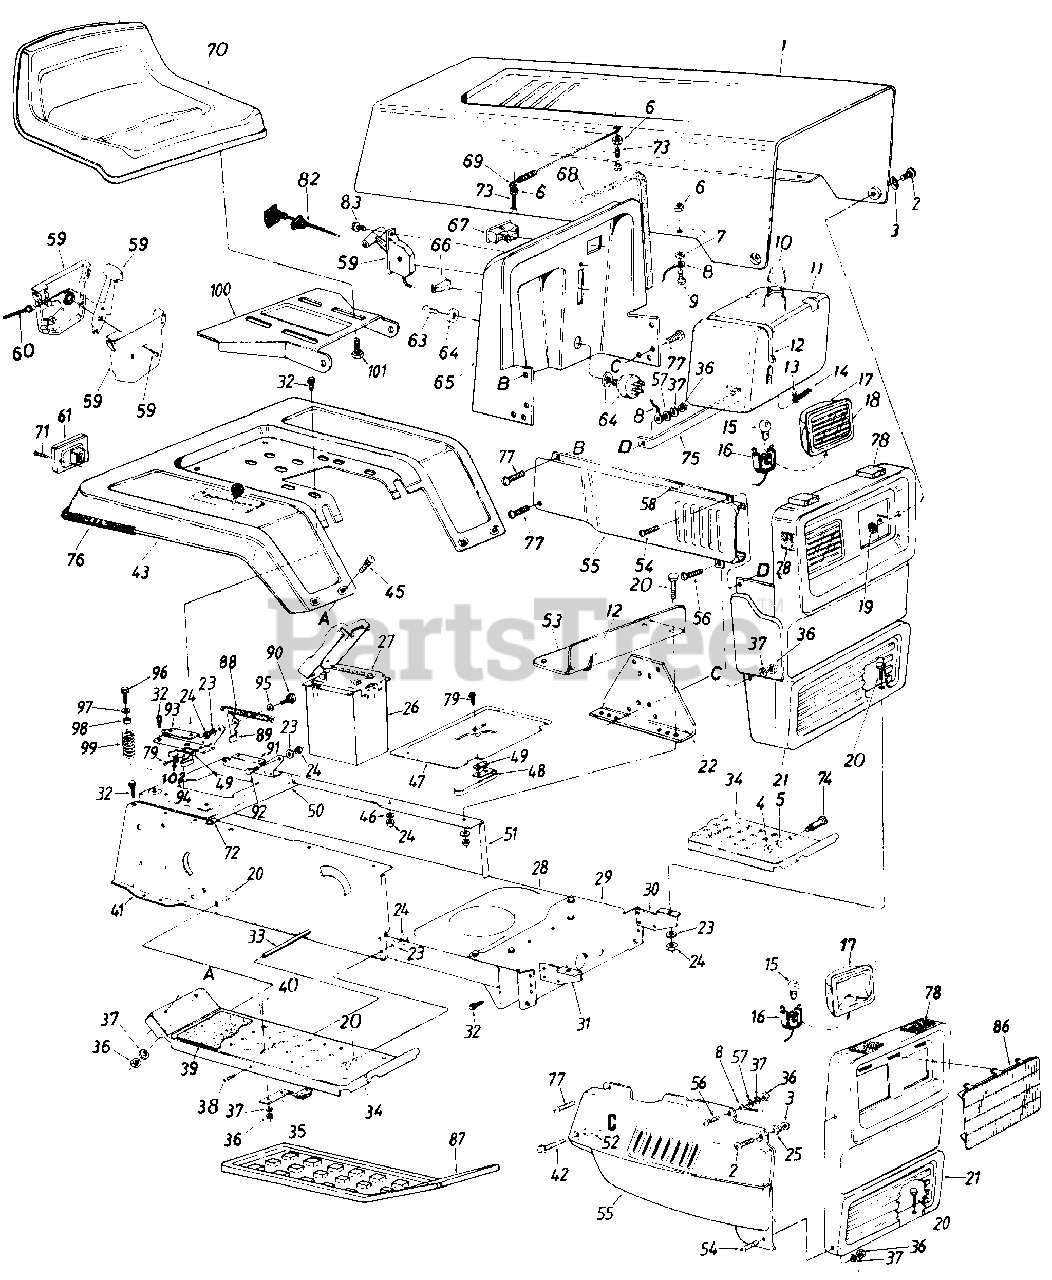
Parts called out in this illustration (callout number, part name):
1	Hood
2	Shld. Bolt .375 Dia. x .125
3	Washer .39" I.D. x .62"
4	Hex Nut 3/8-16 Thd.*
5	L-Wash. 3/8" I.D.
6	Hex Sems Nut #10-24 Thd.
7	Fl-Wash. .203 I.D. x .41
8	Hood Stop
9	Truss Hd. Scr. #10-24 x 1/2
10	Fuel Cap Gauge
11	Fuel Tank
12	Tie Strap
13	Hose Clamp
14	Fuel Line
15	Lamp
16	Twist Lock-Lamp Socket
17	Headlight Housing
18	Lens
19	L-Nut 1/4-28 Thd.
20	Hex Bolt 5/16-18 x .75 Lg.
21	Grille
23	L-Wash. 5/16" I.D.
24	Hex Nut 5/16-18 Thd.
25	Shld. Spacer
26	Battery Box w/Cover
27	12V Battery
28	Lower Frame
29	Front Pivot Brk't.
30	Grille Mount Brk't.-L.H.
33	Running Board Rod
34	Running Board
35	Blade Brake Ass'y.
36	Hex Nut 1/4-20 Thd.
37	L-Wash. 1/4" I.D.*
38	Truss Mach. Scr. 5/16-18 x .75" Lg.
39	Foot Pad
40	Carriage Bolt 1/4-20 x .62
41	R.H. Side Frame
42	Hex TT-Tap Scr. 1/4-20 x 1.75 Lg.
45	Carriage Bolt 1/4-20 x 50"
46	External L-Wash. 5/16" I.D.
47	Transmission Panel
48	Reverse Safety Switch
49	Insulator Nut Plate
50	Hitch Plate
51	L.H. Side Frame
52	Spacer 1.30" Lg.
53	Fuel-Tank Support
54	Truss Hd. Scr. 1/4-20 x 75n
55	Side Cover-R.H.
56	Truss Mach. Scr. 1/4-20 x .50" Lg.
57	Fl-Wash. .281" I.D. x .73" O.D.
58	Mounting Clamp
59	Throttle Control Box Ass'y.
60	Throttle Control Wire
61	Taillight
63	Ignition Key
64	Ignition Switch
67	Ammeter
68	Trim Strip-27"
69	Hood Spring
70	Seat 8-7/8" High
71	Truss Hd. AB-Tap Scr. #6 x .62" Lg.
72	Speed Nut #10Z
73	Hex Scr. #10-24 x l.0" Lg.
74	Shld. Bolt .50 Dia. x .84
75	Tie Strap-Grille/Side Panel
76	Trim Strip-81"
77	Hex Wash. Hd. Tap Scr. 1/4 x .75" Lg.
78	Foam Strip 3/8 x 1-1/8" x 1-1/2" Lg.
79	Hex Wash. Hd. AB-Tap #8 x .50" Lg.
82	Choke Control 29n Lg.
83	Truss Mach. AB-Tap Scr. #10 x .5" Lg.
86	Headlight Bezel
87	Rubber Foot Pad-L.H.
88	Ext. Spring 5.31" Lg.
89	Seat Lift Brkt.
90	Shld. Bolt .437" Dia.
91	Seat Pivot Brkt. Support-L.H.
92	Shld. Bolt .437" Dia.
93	Seat Pivot Brkt. Support-R.H.
94	Spring Switch
95	Spr-Wash. .445" I.D.
96	Hex Wash. Hd. Tap Scr. 5/16-18 x 1" Lg.
97	Fl-Wash. .344" I.D.
98	Bushing
99	Compression Spring
100	Seat Pivot Bracket
101	Hex Tap Scr. 3/8-16 x .75"
102	Fiber Washer
